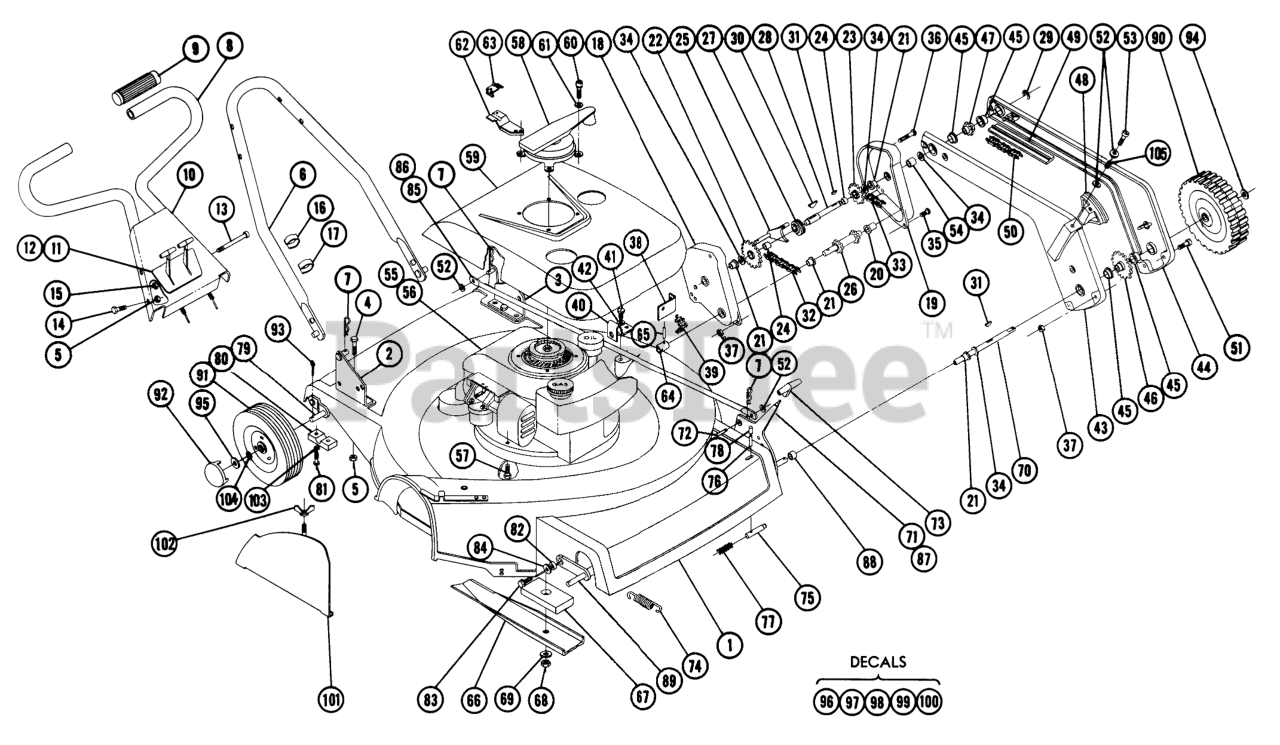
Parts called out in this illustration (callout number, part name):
1	Ass-y. Deck
2	Ass-y. Bracket-Handle R.H.
3	Ass-y. Bracket-Handle L.H.
4	Bolt 5/16-18 x
5	Nut-Nylok
6	Ass-y Handle-Lower
7	Hairpin
8	Handle-Upper
9	Grip-Handle
10	Plate-Control MT-G
11	Control Throttle
12	Control-Throttle & Clutch
13	Screw-Soc. Hd 1/4-28 x 3
14	Bolt-Hex. 5/16-18 x 1
15	Nut-Elastic Stop-1/4-28
16	Clip-Double
17	Clip-Single
18	Case-Trans. R.H.
19	Case-Trans. L.H.
20	BUSHING
21	BRONZE BUSHING
22	Ass-y. Sprocket & Hub
23	Ass-y. Sprocket & Hub
24	Bearing
25	Ass-y Yoke & Shaft
26	Ass-y. Input Shaft & Sprocket
27	Collar-Shift
28	Shaft-Output
29	E Ring
30	HI PRO KEY
31	WOODRUFF KEY
32	Chain-Roller
33	Chain-Roller
34	Washer-Thrust
35	Bolt #10-32
36	Bolt #10-32 x 234 Round Head
37	HEX NUT 10-32 E.S.
38	Bracket-Shift Control
39	Clip-Tinnerman
40	Bracket-Trans. Support
41	Screw 1/4-20 x 5/8 S.T.
42	LOCKWASHER
43	Housing-Drive R.H.
44	Housing-Drive L.H.
45	BUSHING
46	Ass-y.-Sprocket & Hub
47	Ass-y.-Sprocket & Hub
48	Guide-Upper
49	Guide-Lower
50	Chain-Roller
51	Screw-Machine #10-32 x 1 1/4
52	Washer
53	Nut Hex #10-32 Elastic Stop
54	Spacer
55	87SIM-5637/38 WARDS
56	Ass-y. Engine
57	Bolt-Flg. 5/16-18 x 1
58	Ass-y. Starter-Impulse
59	Shroud
60	Screw & L.W. Ass-y. 1/4-28 x 5/8 Fil. Hd.
61	Washer
62	Bracket-Starter Release
63	Clip-Tinnerman
64	Coupling
65	Roll Pin
66	Blade
67	Plate-Blade Drive
68	Nut 5/18 Elastic Stop
69	Washer, 5/8
70	Axle-Front
71	Ass-y. Lever-Height Adj.
72	Screw
73	Knob
74	Spring
75	HOSE BARB,1/4 NPT X 3/8
76	Roll Pin 1/8 x 1 1/8
77	PLUNGER SPRING
78	Cap
79	Ass-y Axle-Rear
80	Cap-Rear Axle Support
81	Screw-Hex. Hd. Slotted, #10-24 x 3/4
82	Spacer
83	Screw & L.W. Ass-y. 5/16-18 x 1 Hex S.T.
84	Washer
85	Rod-Wheel Adj. Link
86	Rod-Wheel Adj. Link
87	Ass-y. Lever-Height Adj. Front
88	Spacer
89	Axle
90	Ass-y.-Wheel Front
91	84 Washer
92	Cap-Hub
93	Hairpin
94	Washer
95	Washer
96	4XC6485 GIS ROTARY
97	Decal-Height Indicator
98	Decal-Reo
99	Decal-Caution
100	Decal-Chain Adjustment
101	Ass-y Leaf Mulcher
102	Nut-Wing 1/4-20
103	Lockwasher #10 External
104	Washer
105	Spring
